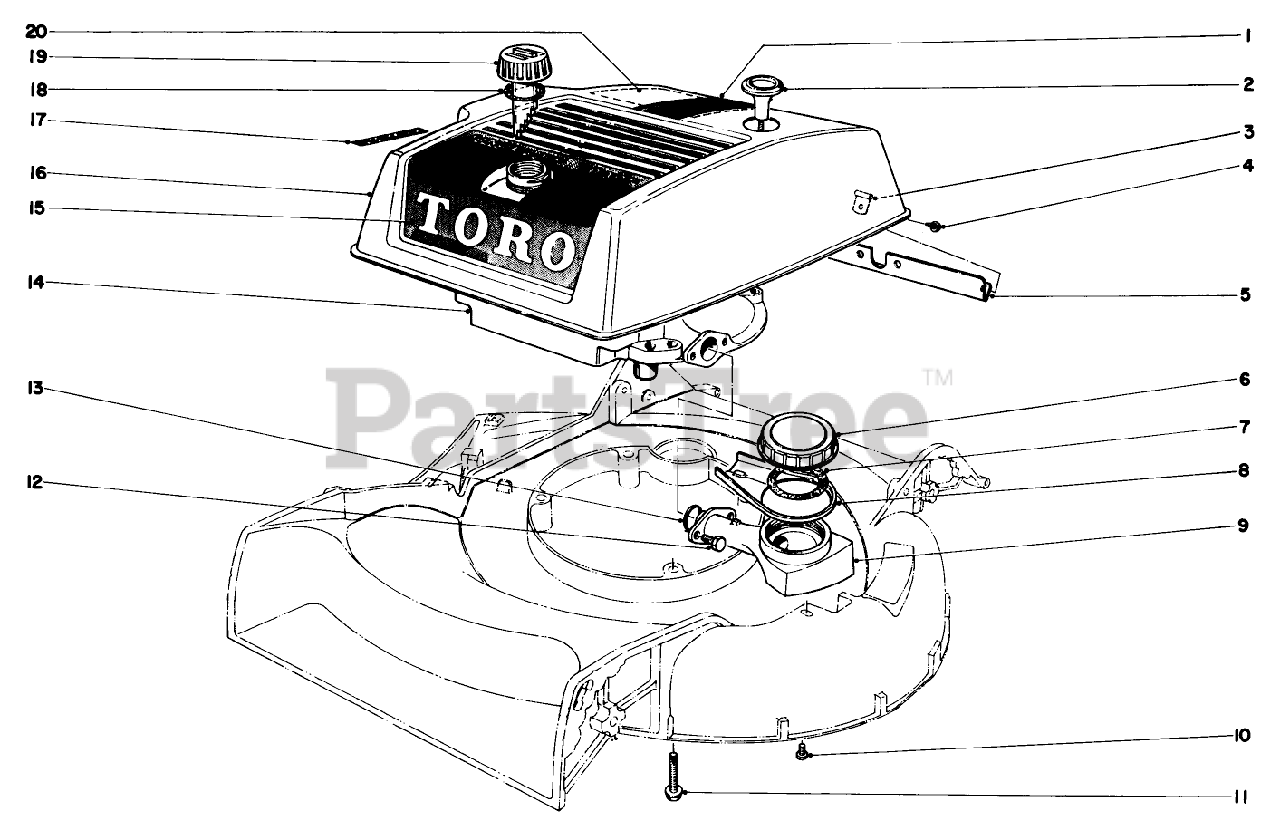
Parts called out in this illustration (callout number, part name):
1	Decal
3	Hinge
4	SCREW-HWHTF
5	Shroud Bracket
9	Oil Gauge
11	3/8-16 X 2-3/4 CAPSCR
13	O RING
14	Engine
15	Decal
18	Gasket
20	Decal-Maintenance
